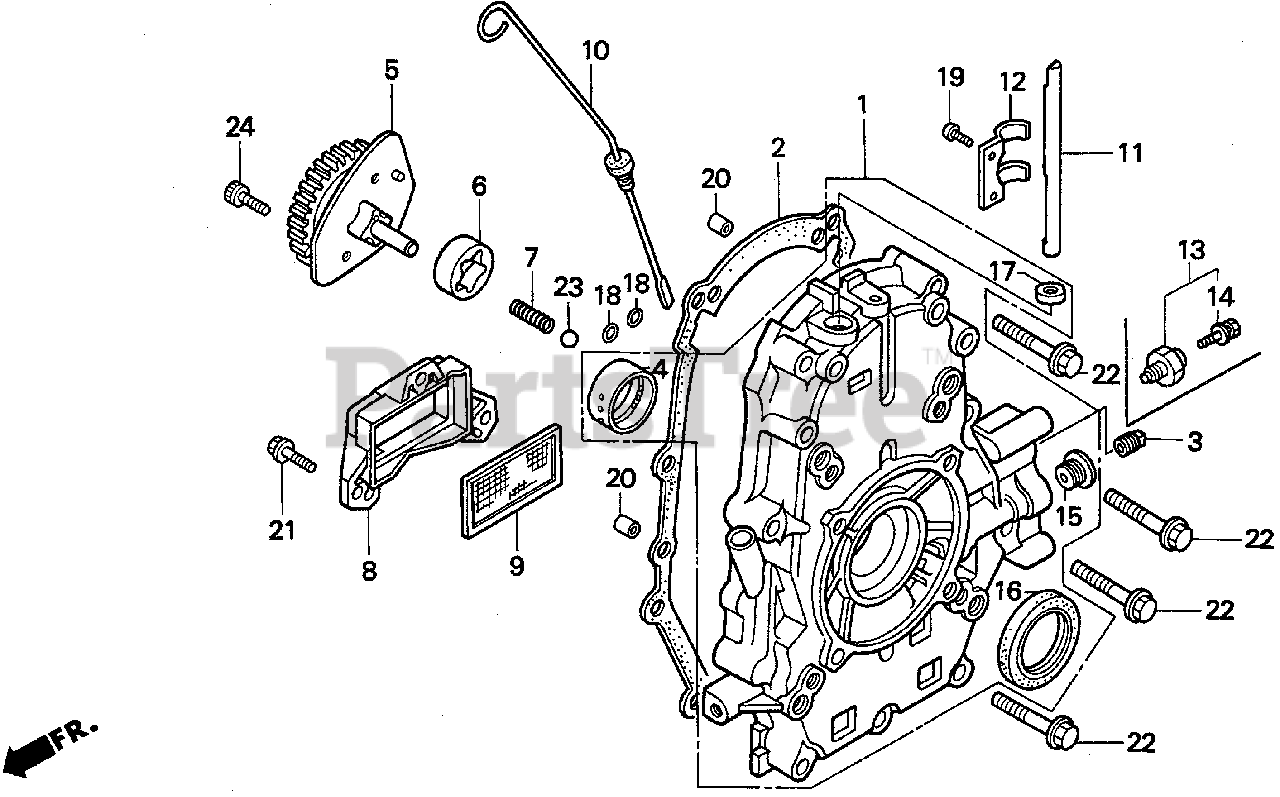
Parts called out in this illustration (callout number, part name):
1	COVER ASSY., CRANKCASE
2	GASKET, CASE COVER
4	BEARING A, MAIN (TO SELECT CORRECT BEARING, SEE THE SERVICE MANUAL.)
4	BEARING B, MAIN (TO SELECT CORRECT BEARING, SEE THE SERVICE MANUAL.)
4	BEARING C, MAIN (TO SELECT CORRECT BEARING, SEE THE SERVICE MANUAL.)
5	COVER ASSY., OIL PUMP
6	ROTOR, OIL PUMP (OUTER)
7	SPRING, RELIEF VALVE
8	COVER, OIL FILTER
9	SCREEN, OIL FILTER
10	DIPSTICK, OIL
11	SHAFT, GOVERNOR ARM
12	FORK, GOVERNOR
13	SWITCH, OIL PRESSURE
14	SCREW-WASHER (4X8)
15	BOLT, SEALING
16	OIL SEAL (38X58X11)
17	OIL SEAL (10X16X4.5)
18	O-RING (13X3.0)
19	SCREW, PAN (5X10)
20	PIN A, DOWEL (8X14)
21	BOLT, FLANGE (6X20)
22	BOLT, FLANGE (8X50)
23	BALL, STEEL (#12) (3/8)
24	BOLT, SOCKET (6X16)
